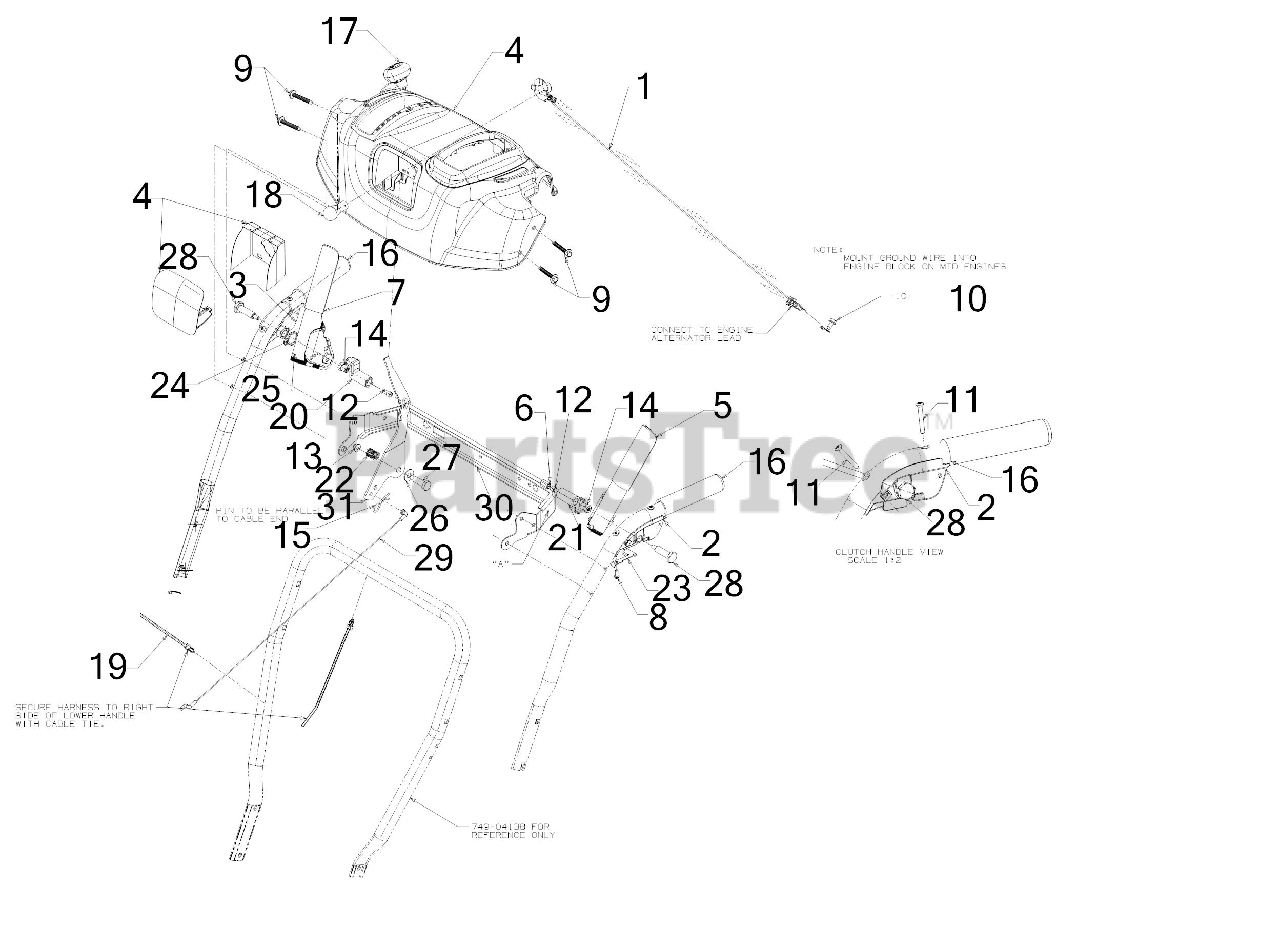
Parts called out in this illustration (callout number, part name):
1	LIGHT HARNESS ASSEMBLY
2	CLUTCH LOCK HANDLE ASSEMBLY (LH)
3	CLUTCH LOCK HANDLE ASSEMBLY (RH)
4	HANDLE PANEL ASSEMBLY (BLACK)
5	HANDLE ASSEMBLY (LH)
6	PIVOT ROD
7	ENGAGEMENT HANDLE ASSEMBLY (RH) (BLACK)
8	SCREW #8-16 x .50
9	SCREW 1/4-20 x 1.625
10	SCREW 1/4-20 X.500
11	SCREW #10-24 x 1.375
12	SCREW 1/4-20 x .50
13	FLANGE LOCK NUT
14	HEX NUT W/PATCH
15	INTERNAL COTTER PIN
17	SHIFT KNOB
18	LAMP-12V
19	PUSH MOUNT TIE
20	LOCK PLATE
21	CLUTCH LOCK CAM
22	COMPRESSION SPRING
23	CLUTCH SPRING
24	TORSION SPRING
25	RUBBER BUMPER
26	FLAT WASHER
27	SHOULDER SCREW
28	SHOULDER SCREW .437 x 1.345 1/4-20
29	SPEED SELECTOR CABLE (PLASTIC)
30	HANDLE SUPPORT BRACKET
31	SHIFT LEVER
